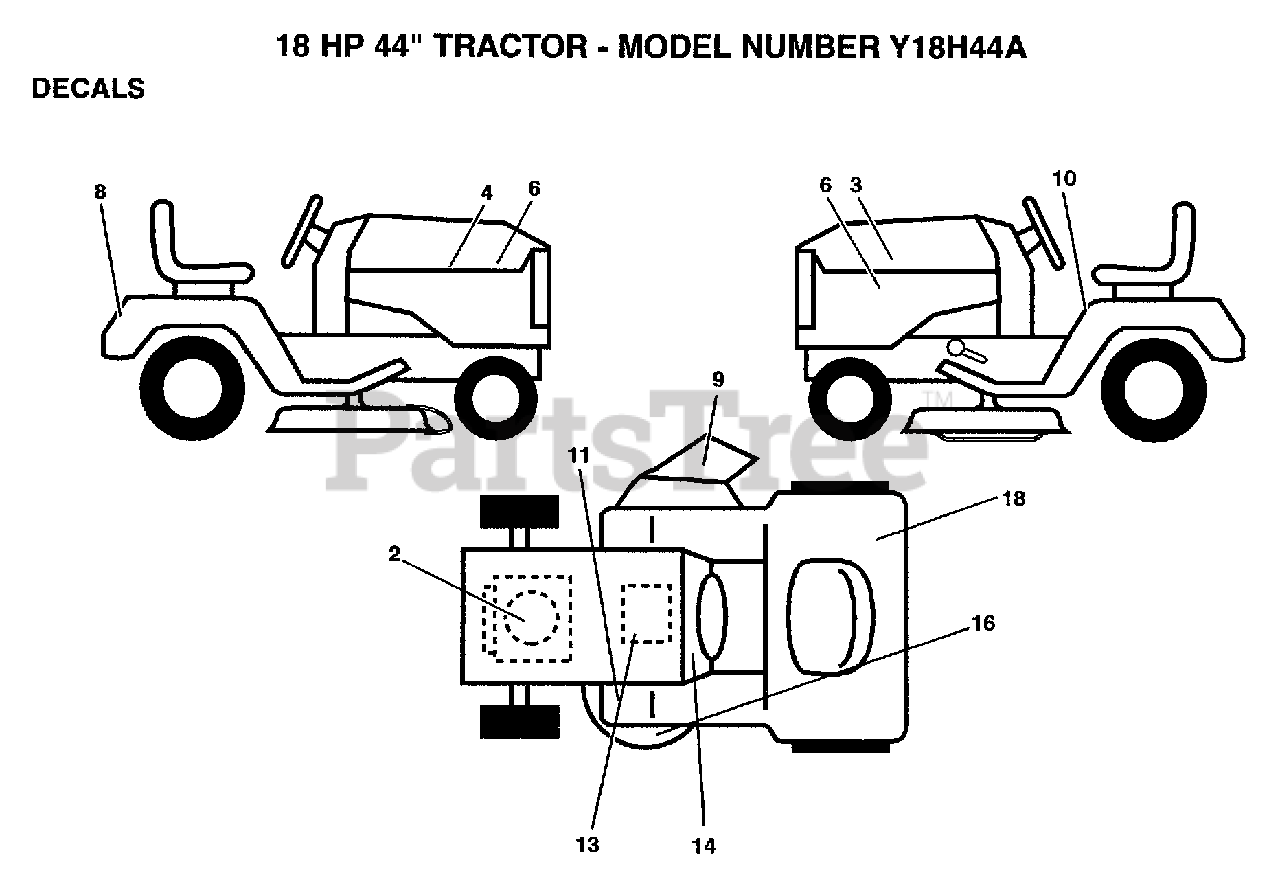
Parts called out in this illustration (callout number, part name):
2	"DECAL,HP ENGINE"
3	DECAL HOOD LH
4	DECAL HOOD RH
6	DECAL PANEL SIDE
11	DECAL CLUTCH BRAKE E/F
16	DECAL ROTATING BLADES
